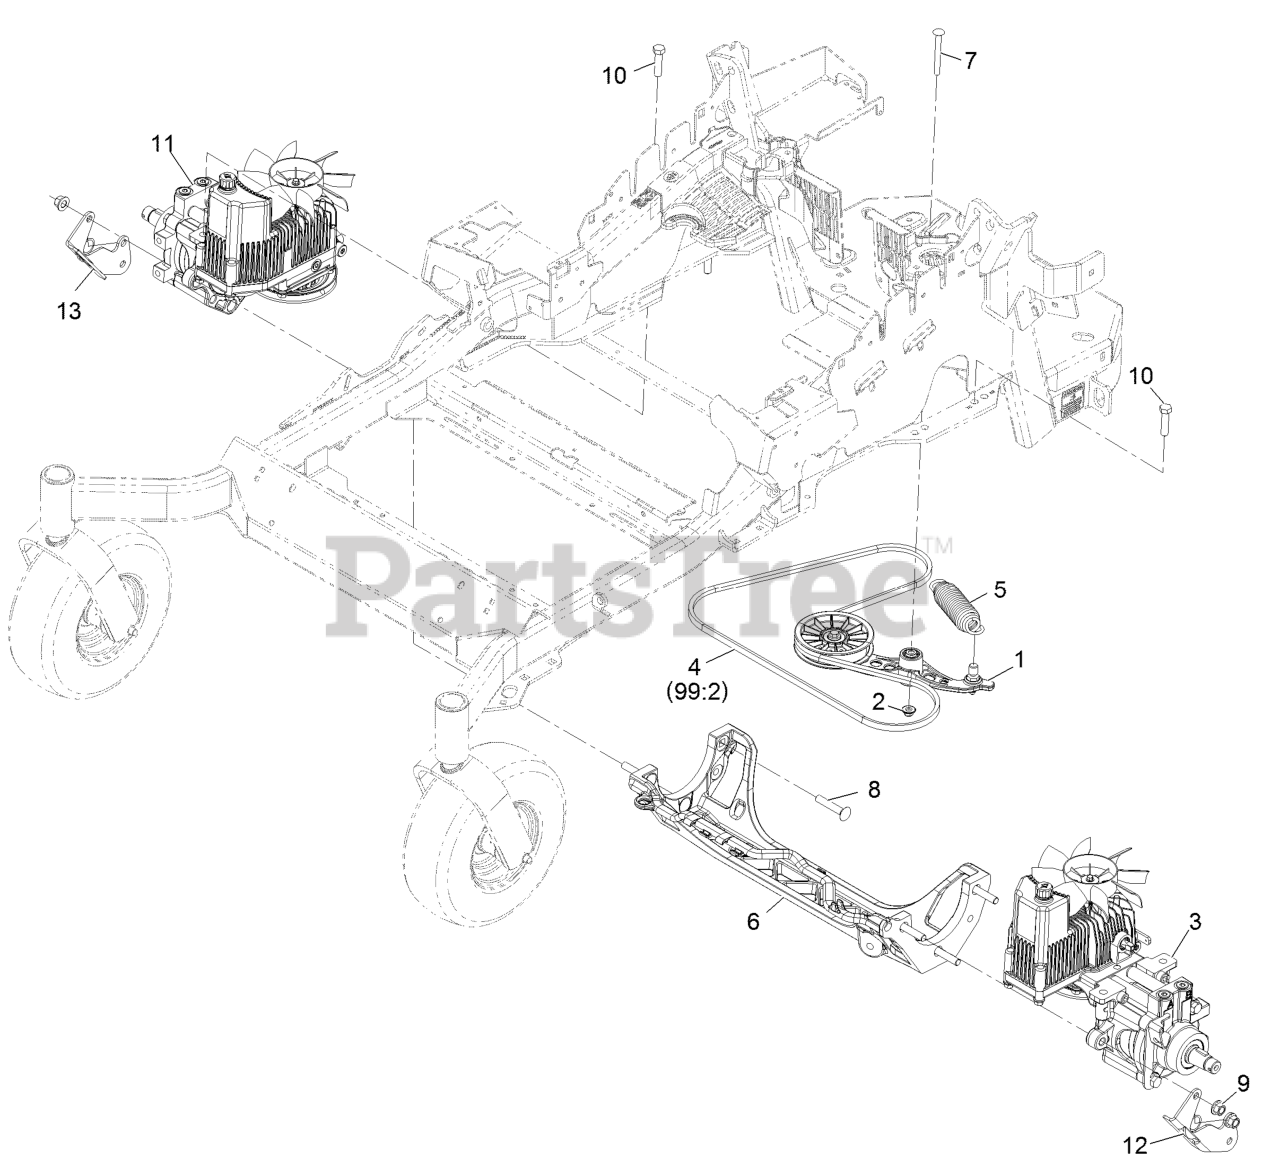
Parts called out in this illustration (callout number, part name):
1	PUMP IDLER ASM
2	Nut-Nyloc 3/8-16 Flg
4	BELT
5	SPRING-EXTENSION
7	BOLT-SHOULDER, CARRIAGE 3/8-16 X 3 1/2
8	SCREW-CARR
9	Nut-Lock 1/2-13
10	SCREW-HH
12	BRACKET-DISCHARGE MOUNT,
13	BRACKET-DISCHARGE MOUNT,
99:2	BELT
